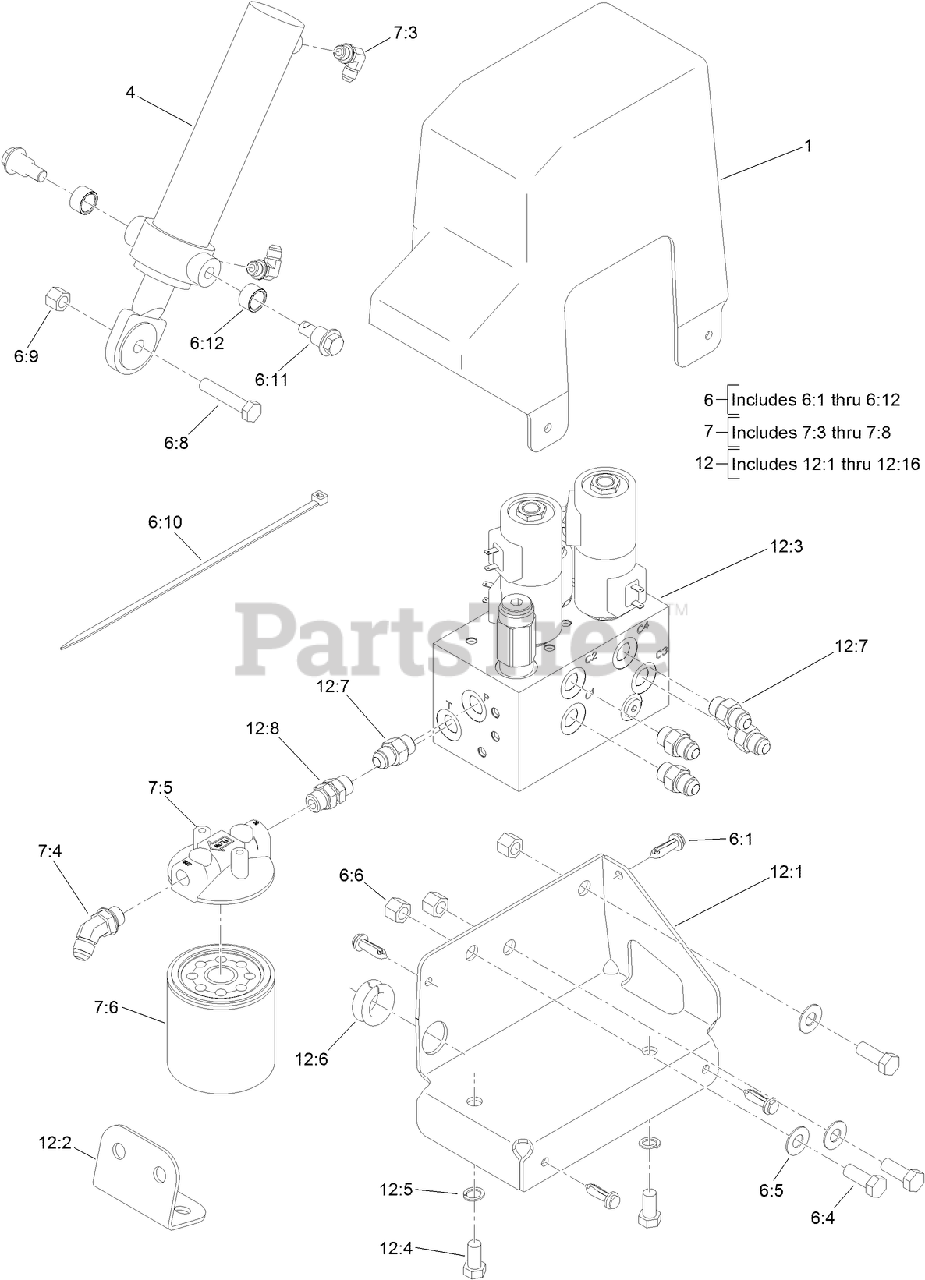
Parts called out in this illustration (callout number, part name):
1	COVER,MANIFOLD,GRANDSTAND
4	CYLINDER,LIFT,2X8
6	KIT-HDW,GRANDSTAND,VEHICLE SIDE
6:1	TUFLOK RIVET
6:4	HHCS,3/8-16X1 NC GR5 PLT
6:5	WASHER,FLAT,3/8ST/ST 18-8
6:6	NUT,3/8-16,NYL INS,YZN
6:8	HHCS,1/2-13X2-1/2,GR5,PLT
6:9	NUT,1/2-13,NYL INS,YZN
6:10	CABLE TIES, (15) COUNT, 50#, 15-1/2,
6:11	BOLT,SHOULDER,PIVOT
6:12	BUSHING,.75X.75
7	KIT-HOSE,GRANDSTAND,VEHICLE SIDE
7:3	FITTING,90,6-MORB X 6-M37JIC
7:4	FITTING,45,6-MORB X 6-M37JIC
7:5	HEAD,FILTER,-06ORB
7:6	ELEMENT,FILTER,WINTER
12	MANIFOLD ASM,GRANDSTAND
12:1	BRACKET,HYD MAN,GRANDSTAND
12:2	MOUNTING BRACKET,BULKHEAD
12:3	MANIFOLD,HYD,CONT. FLOW,2 CYL
12:4	HHCS,3/8-16X3/4 GR5 PLT
12:5	WASHER,3/8,SPLIT LOCK,YZN
12:6	GROMMET,3/4 ID X 1OD X 1/4GROOVE,TGS
12:7	FITTING,STRAIGHT,6-MORB X 6-M37JIC
12:8	FITTING,STRAIGNT,6-MORB X 6-MORB
